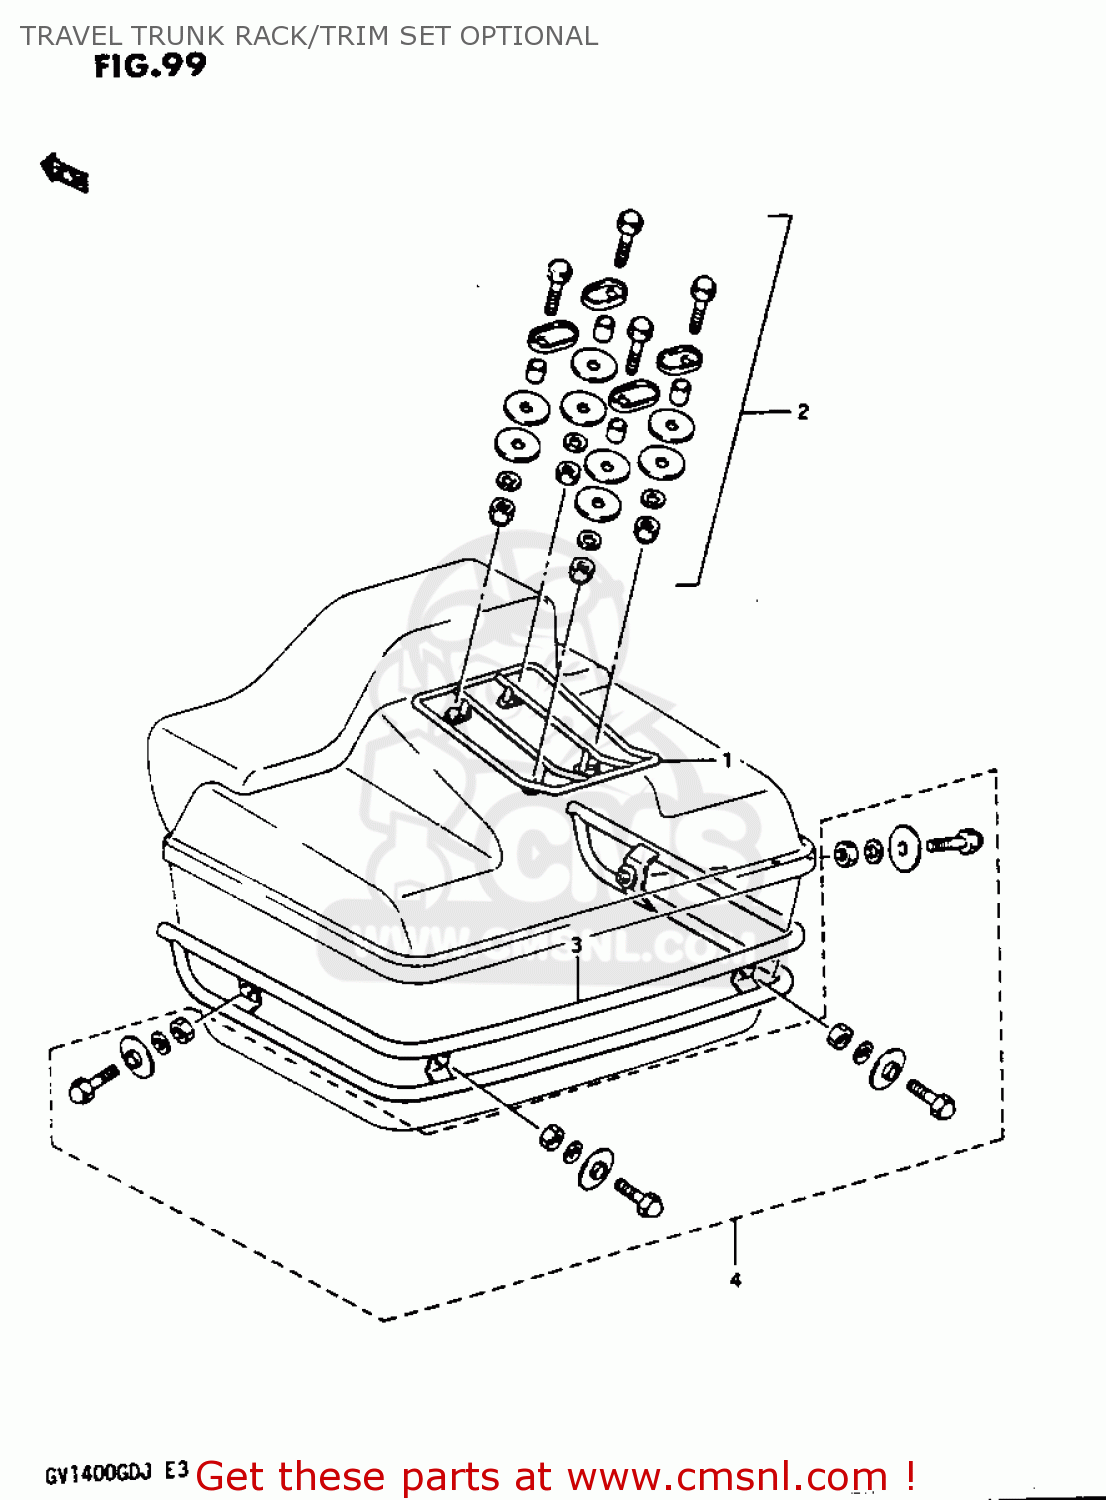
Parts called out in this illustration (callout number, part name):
1	RACK SET, TRAVEL TRUNK
2	FITTING SET, TRUNK RACK
3	TRIM SET, TRAVEL TRUNK
4	FITTING SET, TRUNK TRIM
